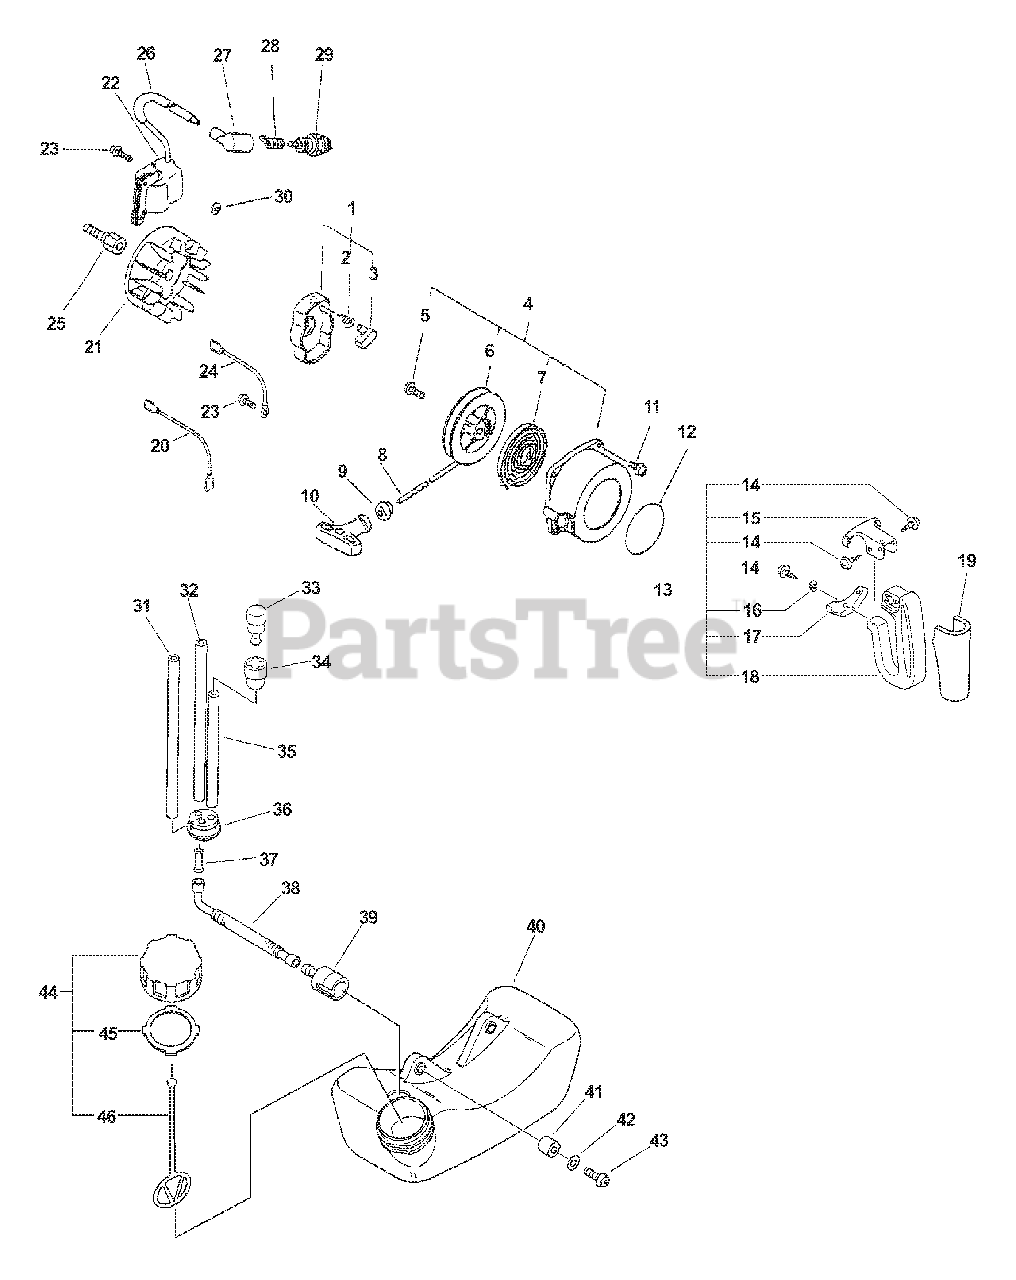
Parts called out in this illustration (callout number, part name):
1	PAWL ASSY, STARTER
2	SPRING, RETURN
3	PAWL, STARTER - BLACK
4	STARTER ASSY, RECOIL
5	SCREW
6	REEL, ROPE
7	SPRING, RECOIL
9	GUIDE, ROPE
10	GRIP, STARTER
11	BOLT 4×16
12	LABEL, ECHO
13	HANDLE ASSY, SIDE
14	SCREW 5×16
15	BRACKET, UPPER HANDLE
16	WASHER, SPRING 5
17	BRACKET, LOWER HANDLE
19	GRIP, HANDLE
20	LEAD - GROUND
20	LEAD - IGNITION
21	FLYWHEEL
22	COIL, IGNITION
23	SCREW 4×22
24	LEAD
25	HUB, FAN
27	CAP, SPARK PLUG
28	TERMINAL, SPARK PLUG
29	SPARK PLUG - BPM-7Y
29	SPARK PLUG - BPMR7A
31	PIPE, FUEL RETURN 3×6×90 MM CLEAR
32	PIPE, FUEL 3×5×90 BLACK
33	VENT ASSY
34	HOLDER, VENT
35	PIPE, FUEL 3x-5x-70 BLACK
36	GROMMET, FUEL
37	CONNECTOR, PIPE
38	PIPE, FUEL 3×7×100 FLEXIBLE
39	FILTER, FUEL
40	TANK ASSY, FUEL
41	SPACER 6.2×7.8×6
42	WASHER 5.5×12×0.8
43	SCREW 5×16
44	CAP ASSY, FUEL
45	GASKET, FUEL CAP
46	CONNECTOR, CAP L= 100 MM
